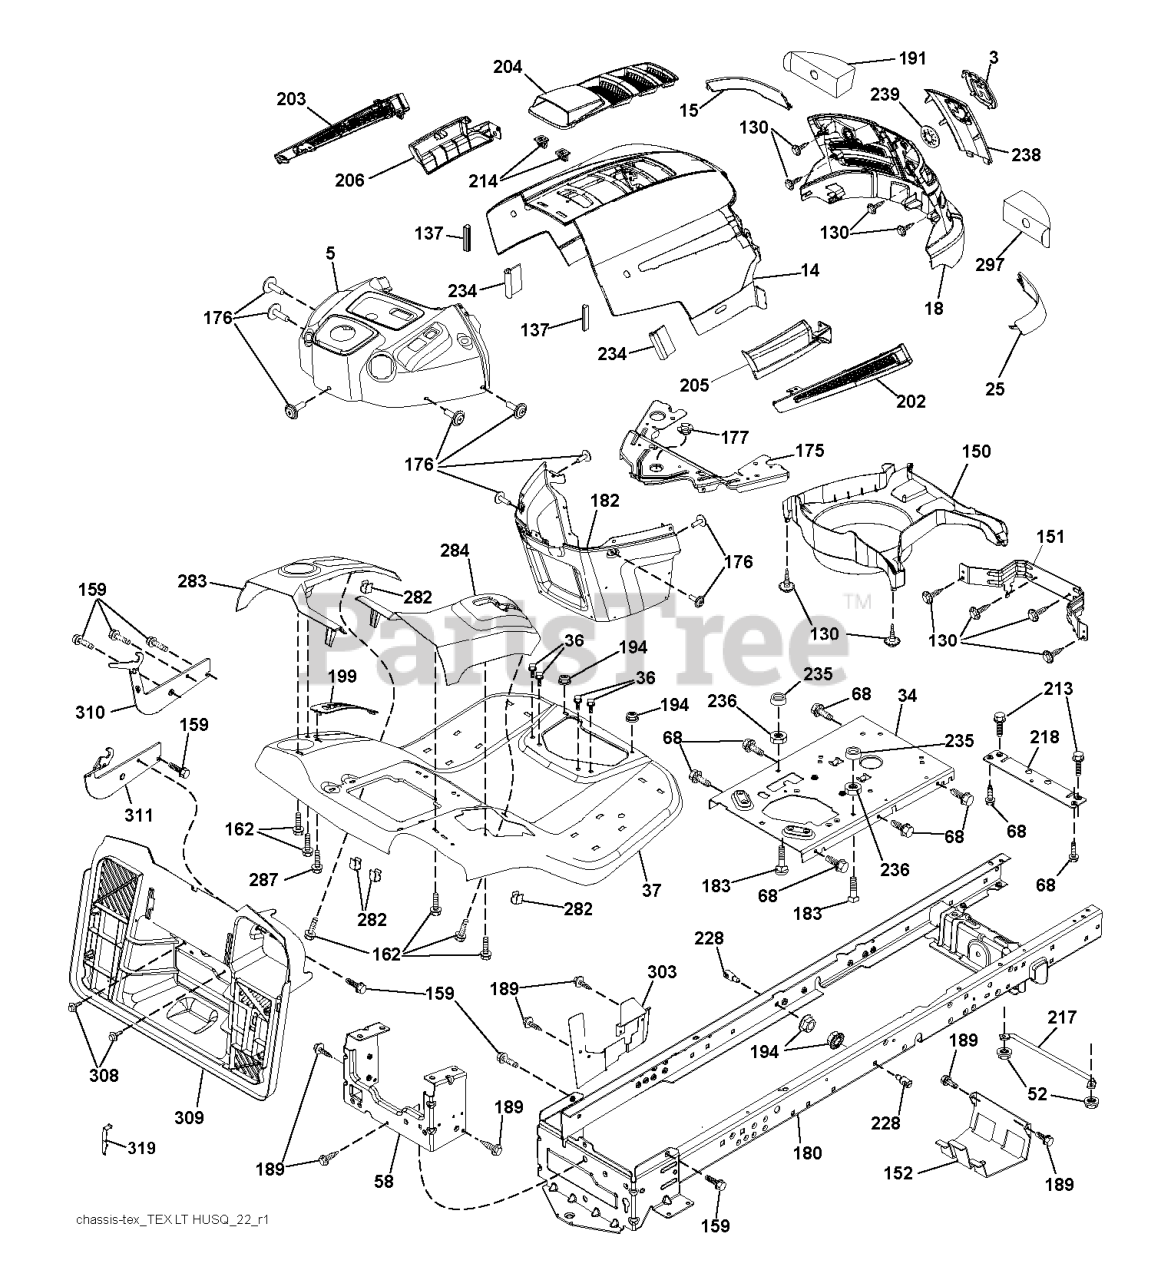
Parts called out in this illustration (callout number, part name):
3	RP LOGO
5	DASH
14	HOOD.HUSQVARNA.LT.MS422
15	LENS.HUSQVARNA LT.LH
18	RP GRILLE/LENS ASM.
25	LENS.HUSQVARNA LT.RH
34	PLATE.ENGINE.WELDED.CHASSIS
36	SCREW 5/16"
37	FENDER.PNT.SRD.30R
52	LOCKNUT
58	DRAWBAR UPPER 2PC SMALL FENDER
68	Screw 5/16-18 x 1/2 Hex, Self Tapping 5/16-18 x 1/2
130	SCREW.#10 X 0.750.BOS
137	BUMPER DASH
151	BRACKET PIVOT
152	SHIELD.BROWNING.W/TEX
159	SCREW, 3/8-16X3/4
162	SCREW.HI-LO.CONSOLE
175	CROSSMEMBER
176	SCREW.#10-24X5/8.RN.QU
177	BUSHING STEERING
180	CHASSIS.WLDMNT.14GA.2PC.18".TI
182	DASH.LOWER.PREDATOR LT
183	BOLT.5/16-18X1-1/4 FULL.THREAD
189	SCREW
191	INSERT REFLECTIVE
194	NUT LOCK HEX FLANGE 5/16-18
199	PLATE DECK LIFT
202	VENT SIDE HOOD RH
203	VENT SIDE HOOD LH
204	VENT TOP HOOD
205	SKIRT SIDE RH
206	SKIRT SIDE LH
213	BOLT
214	CLIP.RETAINER.TINNER.
217	ROD.PIVOT.HOOD
218	X-PIECE.HOOD.STOP.NON/
228	STUD.FASTNER.W/ANTI-ROTATE
234	BUMPER.HOOD.TEX.HUSQVARNA
235	SPACER FENDER
236	NUT.CENTERLOCK.5/16-
238	TRIM
282	CLIP.RETAINER.CONSOLE.LT.HUSQ
283	CONSOLE.DCKLFT.SRD.BGR
287	SCREW 1/4X20
297	INSERT.REFLECTIVE.RH.
303	SHIELD CHASSIS LEFT
308	BOLT.5/16-18UNCX3/4 W/SEMS.BLK
309	BACKPLATE.BAGGER.V2.SRD
310	Bracket Hangar Bag LH
311	Bracket Hangar Bag RH
319	BRACKET.ACTUATOR.BAGGER.SRD
